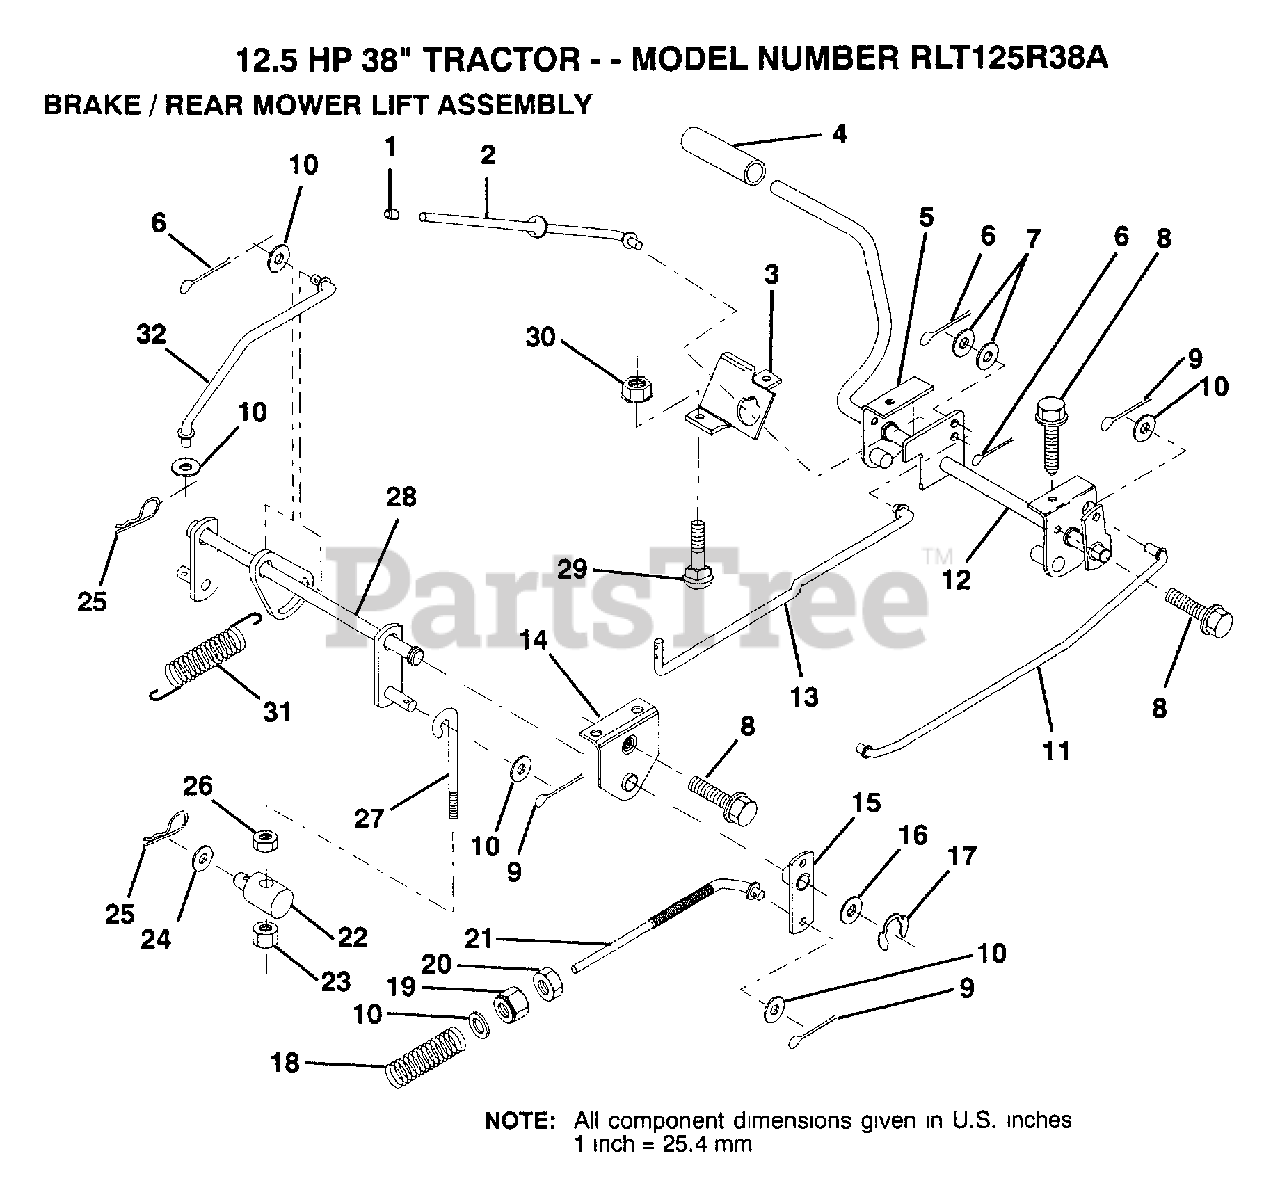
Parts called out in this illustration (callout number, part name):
1	PLUNGER CAP T
2	"ROD,PARK BRAKE"
3	"BRKT,PARK BRAKE"
4	PEDAL COVER T
5	BRK ASM CLUT LH
7	WASHER
8	SCREW LT
9	COTTER PIN
10	WASHER
11	"ROD,FRT BRAKE"
12	ASM CLUTCH/BRK PD
13	"ROD,CLUTCH"
14	"BRKT,LIFT SHAFT"
15	BRAKE PIVOT ARM
16	WASHER T
17	KLIP RING
18	SPRING ROD LT
19	NUT
24	WASHER
25	SPRING.RETAINER
26	LOCKNUT
27	THREADED LINK
28	ASM REAR MOW LIFT
31	COUNTER SPRING
32	LINK LIFT LEVER
